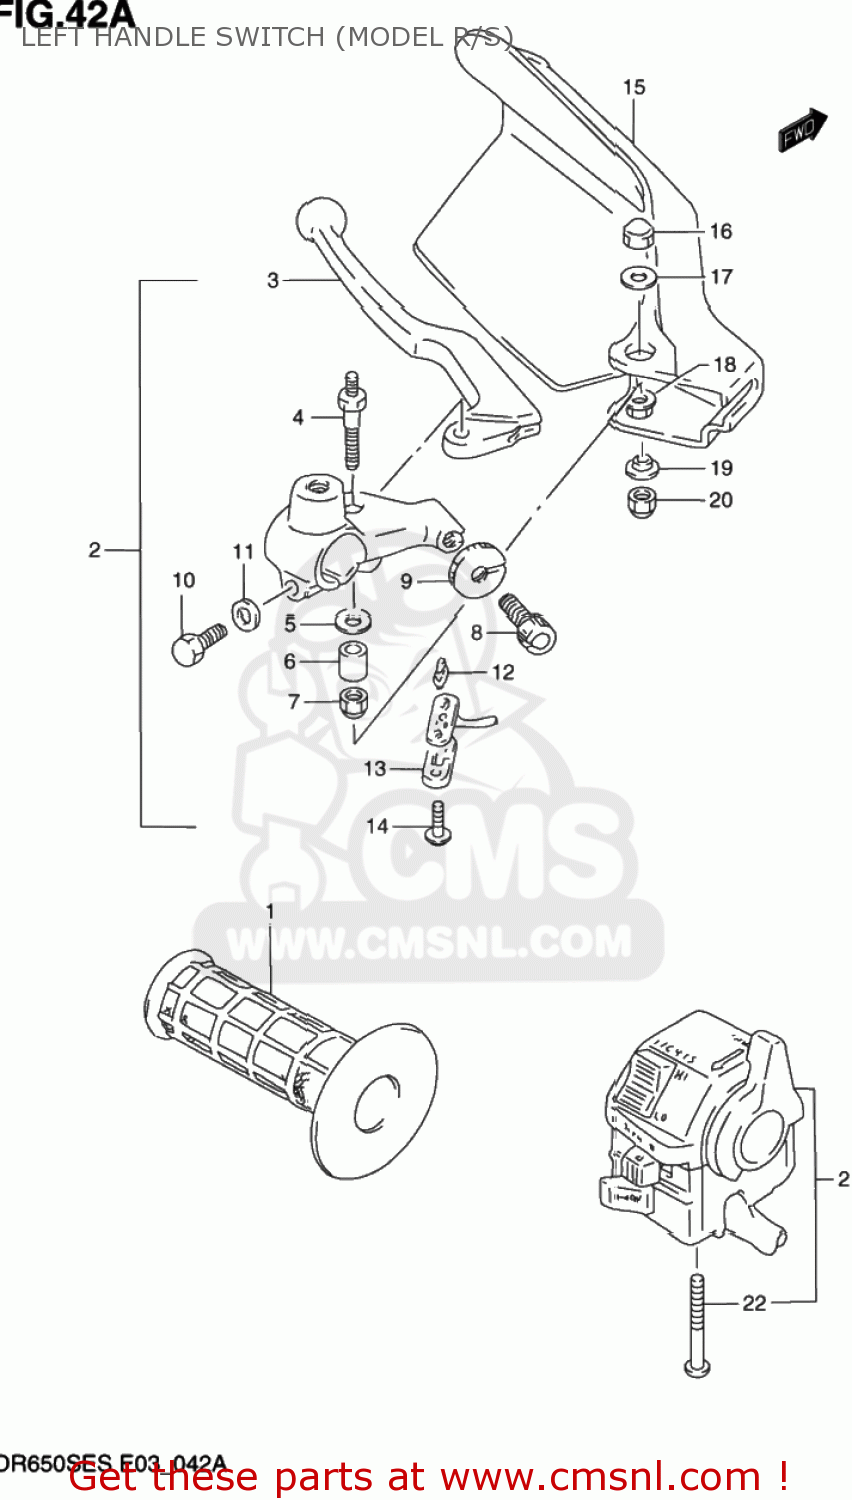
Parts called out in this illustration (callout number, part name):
1	GRIP,L
2	LEVER ASSEMBLY,CLUTCH
3	LEVER,CLUTCH
4	BOLT,LEVER SET
5	WASHER
6	SPACER,LEVER SET
7	NUT
8	ADJUSTER,CABLE
9	NUT,CABLE ADJUSTER
10	BOLT
11	WASHER
12	CONTACT,SWITCH
13	COVER,FR BK TERMINAL BASE
14	SCREW
15	COVER,KNUCKLE,LEFT
16	NUT
17	WASHER(6.5X20X1.6)
18	WASHER(6.5X16X1.2)
19	WASHER
20	NUT 6MM
21	SWITCH ASSEMBLY,HANDLE,LEFT
22	SCREW, 5X45
